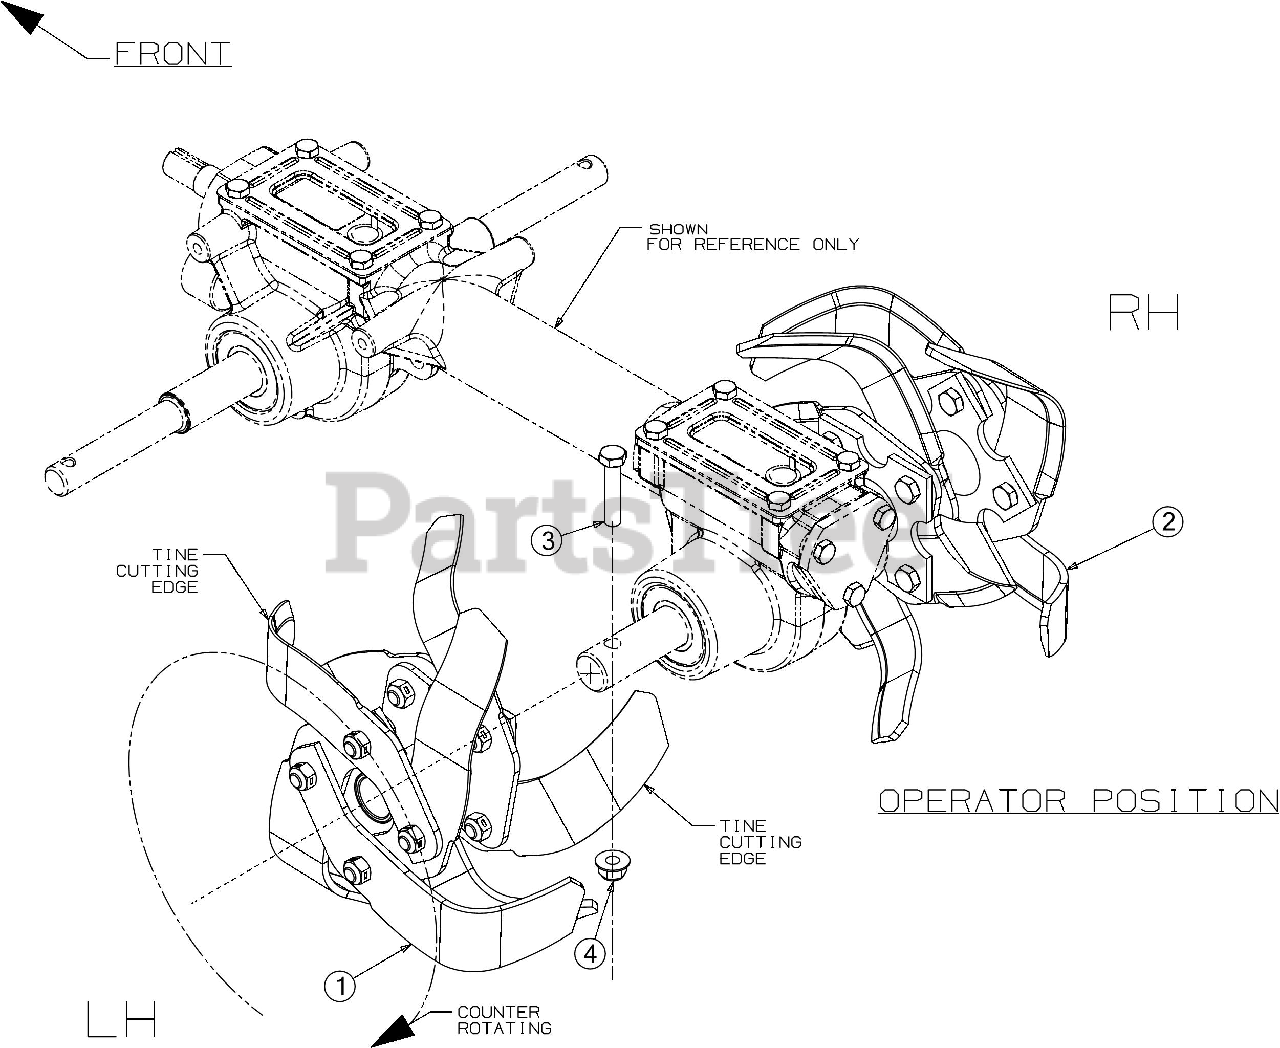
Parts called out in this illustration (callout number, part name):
1	TINE HOLDER ASSEMBLY
1	SCREW 3/8-16 x 1 GR5
1	LOCK NUT 3/8-16
2	TINE HOLDER ASSEMBLY
2	SCREW 3/8-16 x 1 GR5
2	LOCK NUT 3/8-16
3	HEX SCREW 3/8-16 x 1.75 GR5
